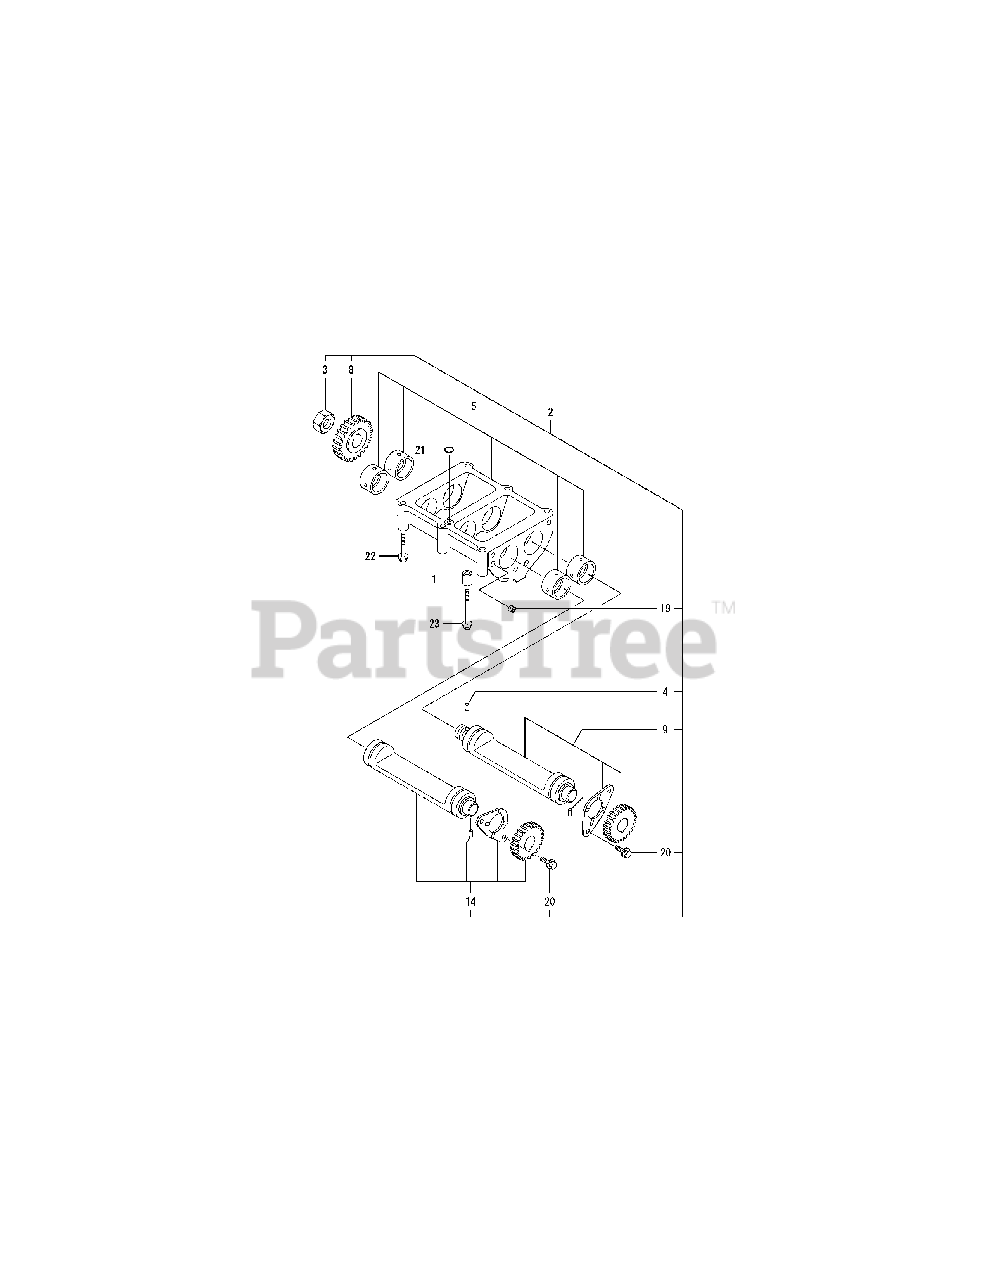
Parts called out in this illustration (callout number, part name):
5	CASE ASSY, BALANCER
8	GEAR, BALANCER A
9	SHAFT, BALANCER A
14	SHAFT, BALANCER B
20	BOLT 8X 14 PLATED
21	O-RING 1A P-14.0
22	BOLT M 8X 60 PLATED
23	BOLT M 8X 80 PLATED
